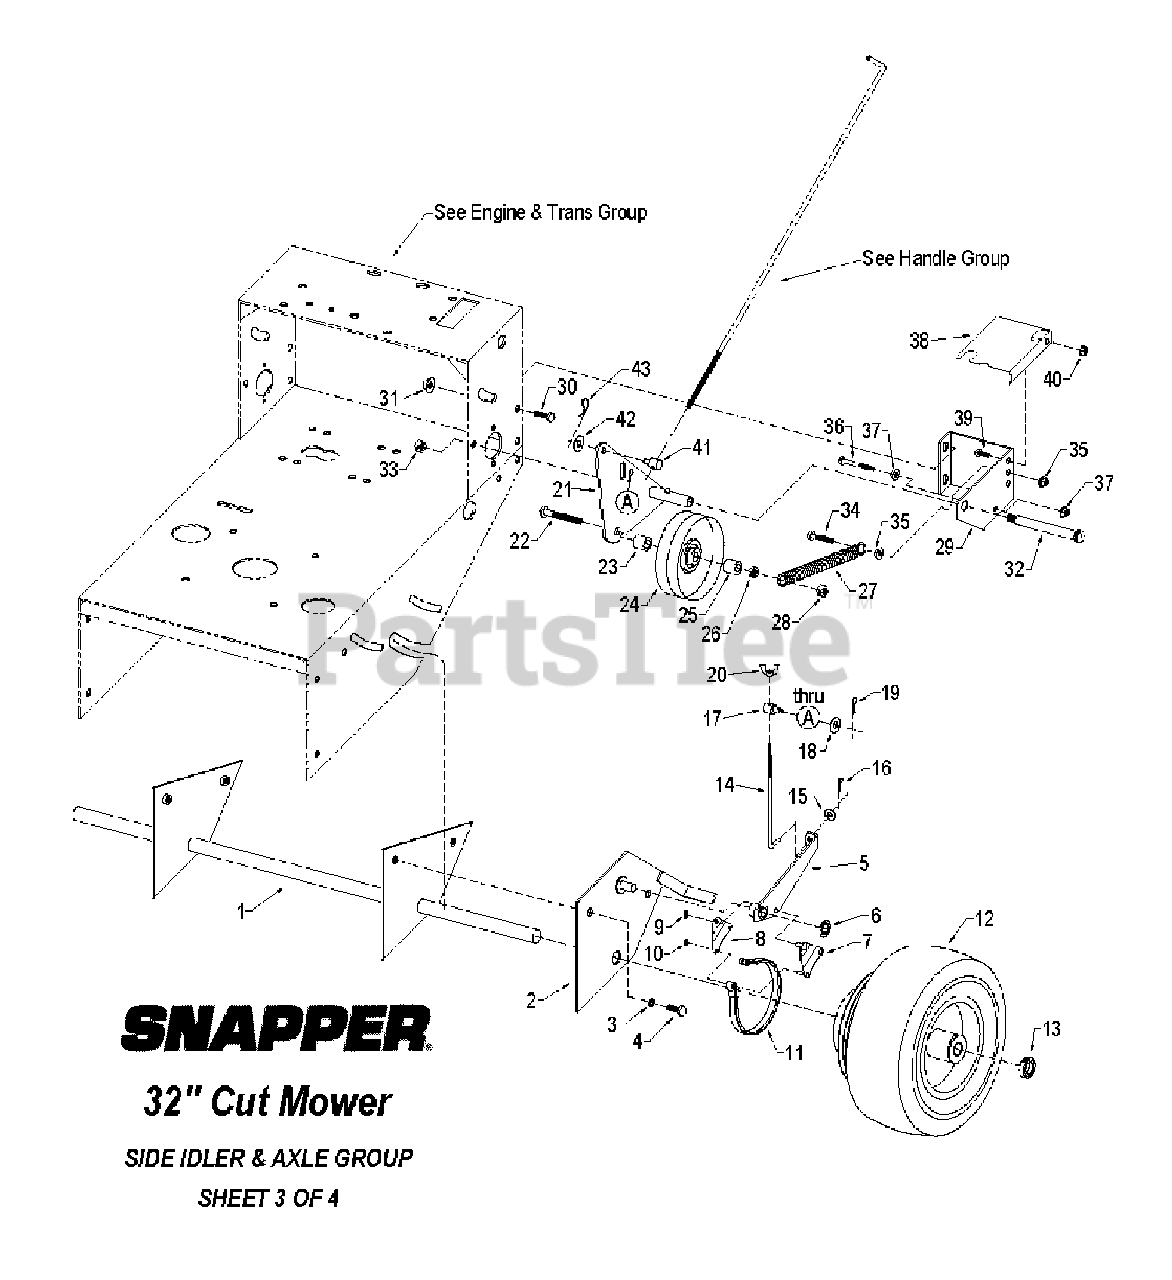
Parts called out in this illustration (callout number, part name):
1	Axle assembly
2	Brake pivot plate - left
3	3/8" lock washer
4	3/8-16 x 1" hex bolt
5	Brake arm - left
6	5/8" retaining washer
7	Brake link plate w/pins
8	Brake link plate - no pins
9	3/8" push-on washer
10	5/16" push-on washer
11	Brake band
12	13-5.00 x 6 wheel & tire assy
13	1" locking collar
14	Lower brake rod
15	5/16" flat washer
16	#2 bridge pin
17	Rod fitting end - unthreaded
18	5/16" flat washer
19	#2 bridge pin
20	5/16-18 wing nut w/nylon insert
21	Side idler plate - left
22	1/2-13 x 3-1/2" hex bolt
23	1/2" I.D. x 5/8" spacer
24	Side idler pulley
25	1/2" I.D. x 3/8" spacer
26	1/2-13 lock nut
27	Side idler tension spring
28	1/2-13 lock nut
29	Side idler spring bracket - left
30	3/8-16 x 1" hex bolt
31	3/8-16 large serrated flange nut
32	5/8 x 4-1/4" shoulder bolt
33	1/2-13 lock nut
34	3/8-16 x 1-1/2" hex bolt
35	3/8-16 small serrated flange nut
36	5/16-18 x 3" hex bolt
37	5/16-18 small serrated flange nut
38	Wheel drive pulley cover - left
39	5/16-18 x 3/4" hex bolt
40	5/16-18 small serrated flange nut
41	Rod fitting end (trunion)
42	5/16" flat washer
43	#2 bridge pin
